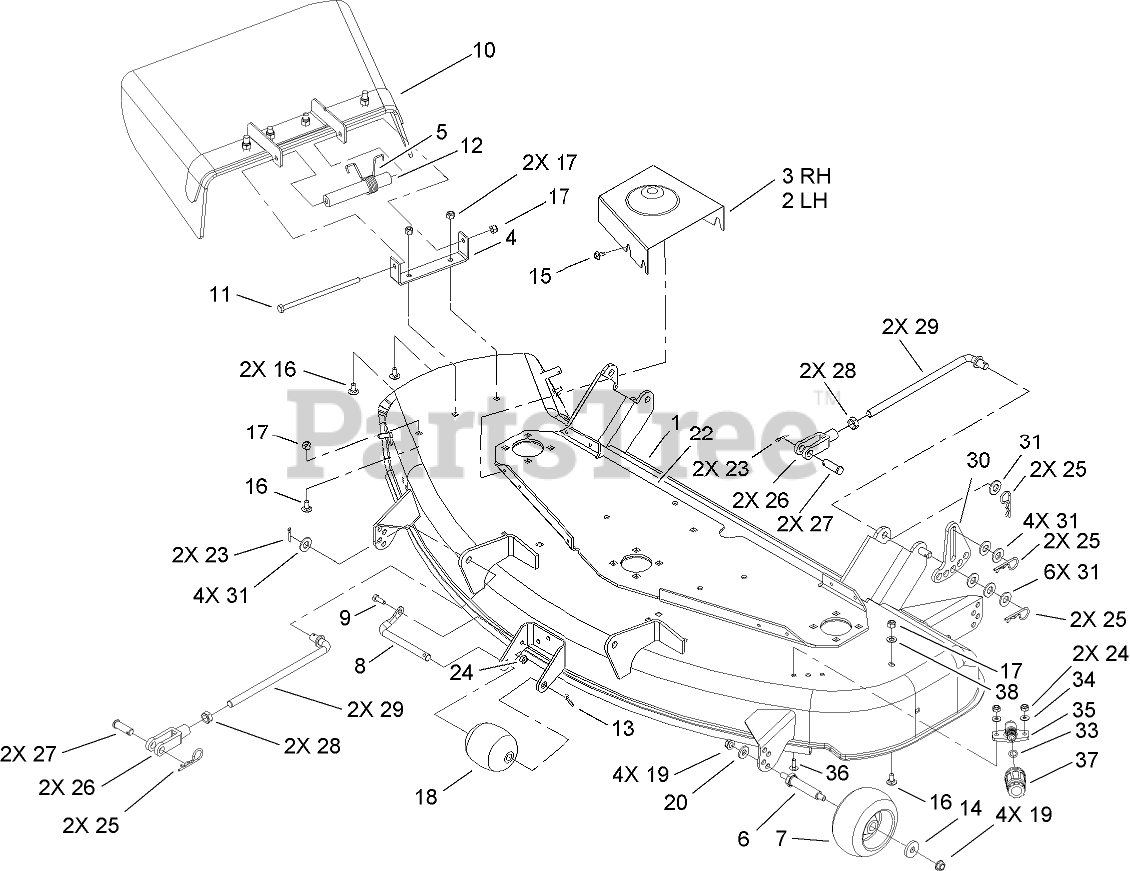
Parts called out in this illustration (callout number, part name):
1	DECK ASM
3	COVER-BELT, RH
4	BRACKET-PIVOT
5	SPRING-TORSION
6	SPACER
7	ROLLER-SCALP, ANTI
8	ROLLER-SHAFT
9	SCREW-HH
10	DEFLECTOR ASM
11	BOLT-HH
12	SPACER-DEFLECTOR
13	PIN-COTTER
14	WASHER
15	SCREW-HHFTF
16	SCREW-CARR
17	NUT-LOCK, NI
18	ROLLER
19	NUT-HHF, WHIZ
20	WASHER-BELLEVILLE
22	PLATE-REINFORCEMENT, DECK
23	PIN-COTTER
24	NUT-LOCK, NI
25	PIN-COTTER
26	CLEVIS
27	PIN-CLEVIS
28	NUT-JAM
29	ROD-TRUNION
30	LINK-HOC, ADJUSTING
31	WASHER-FLAT
33	O-RING
34	WASHER-FLAT
35	FITTING-WASHOUT
36	BOLT-CARR
37	CONNECTOR-HOSE
38	WASHER-PLAIN
